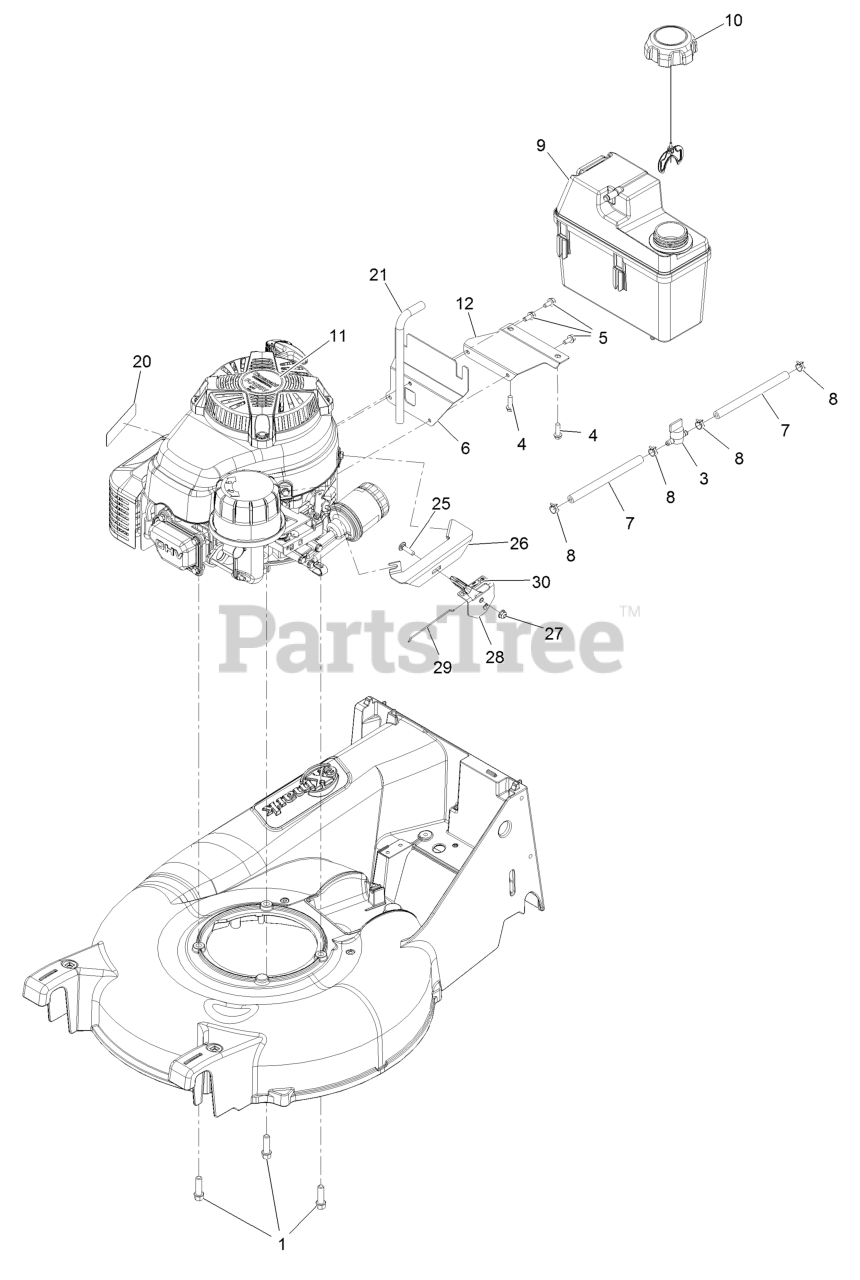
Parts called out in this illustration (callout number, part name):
1	SCREW-TAPTITE
3	VALVE-FUEL
4	SCREW-HWH
5	SCREW-HWH
6	BRACKET-TANK, MOUNTING
7	HOSE-FUEL
8	CLAMP-HOSE
9	TANK-FUEL
12	BRACKET-TANK, SUPPORT
20	DECAL-ARRESTER, SPARK
21	HOSE-VENT, CANISTER
25	SCREW-CARR
26	BRACKET-MOUNT, THROTTLE
28	CONTROL-THROTTLE
29	WIRE-CONTROL
30	DECAL-THROTTLE, CHOKE
